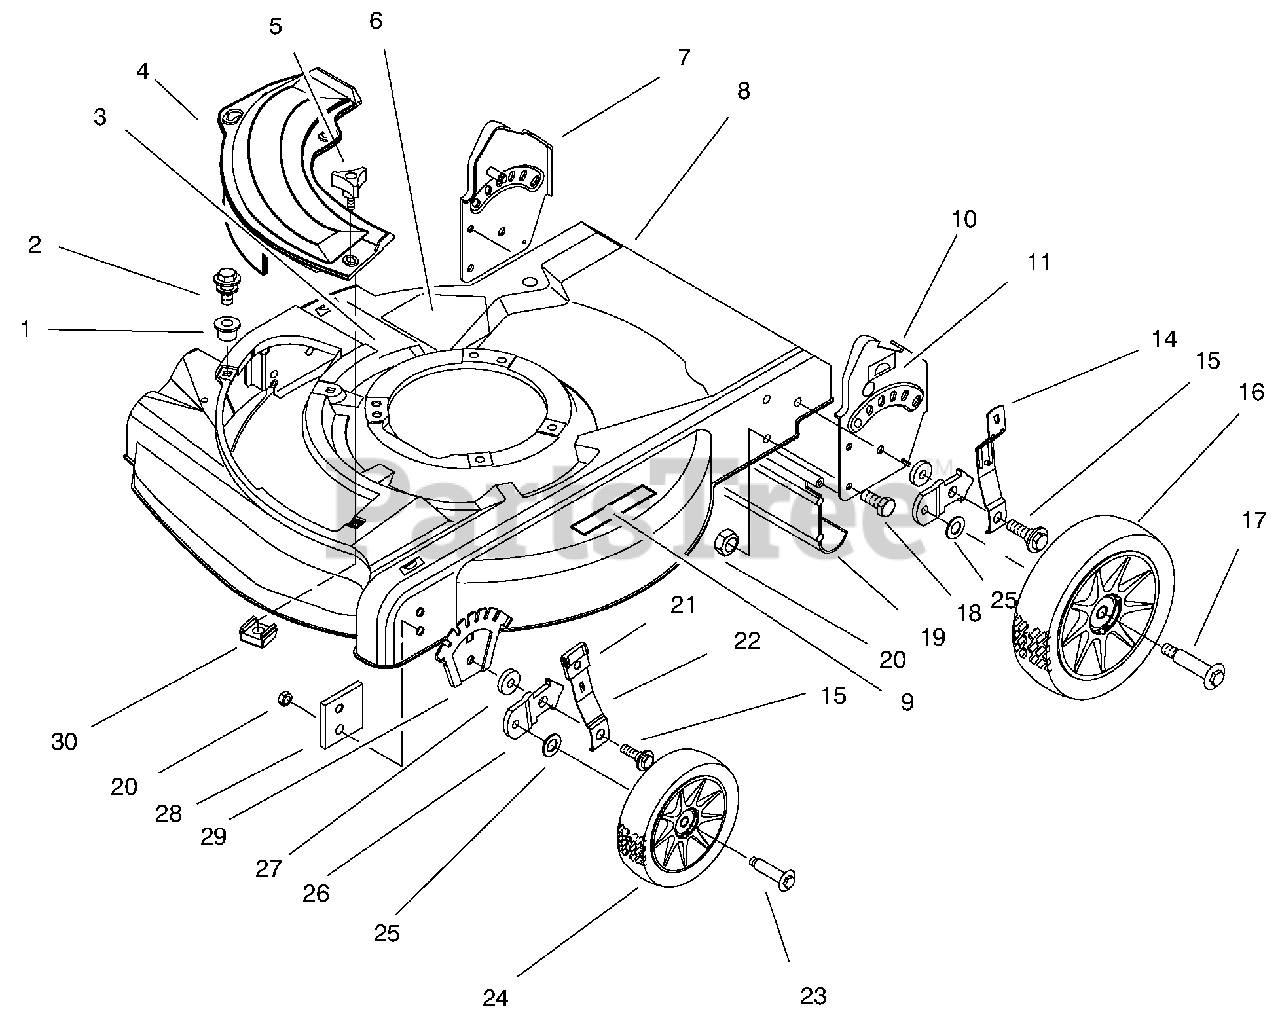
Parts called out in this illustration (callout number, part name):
1	Grommet-Plastic
2	Screw-Thread Forming
3	Decal-Danger
4	Plate-Cover, Mulch
5	Knob
6	Decal-Danger
7	Handle Bracket Ass'y-RH
8	Housing & Baffle Ass'y (Incl. Ref. #1-3, 6, & 9)
9	Decal-Warning
10	Handle Bracket Ass'y-LH
11	Decal-H. O. C. L.H.
14	Spring Arm Assembly
15	Bolt-Shoulder
16	Wheel Ass'y-8"
17	Bolt-Wheel
19	Shield-Trailing
21	Knob-H. O. C. Lever
22	Arm-Spring, Front
23	Bolt-Wheel
24	Wheel Ass'y-6"
25	Washer-Wheel Bolt
26	Bracket-H. O. C.
28	Plate-Baffle
29	Plate-H. O. C. Front
30	Nut-Cage
